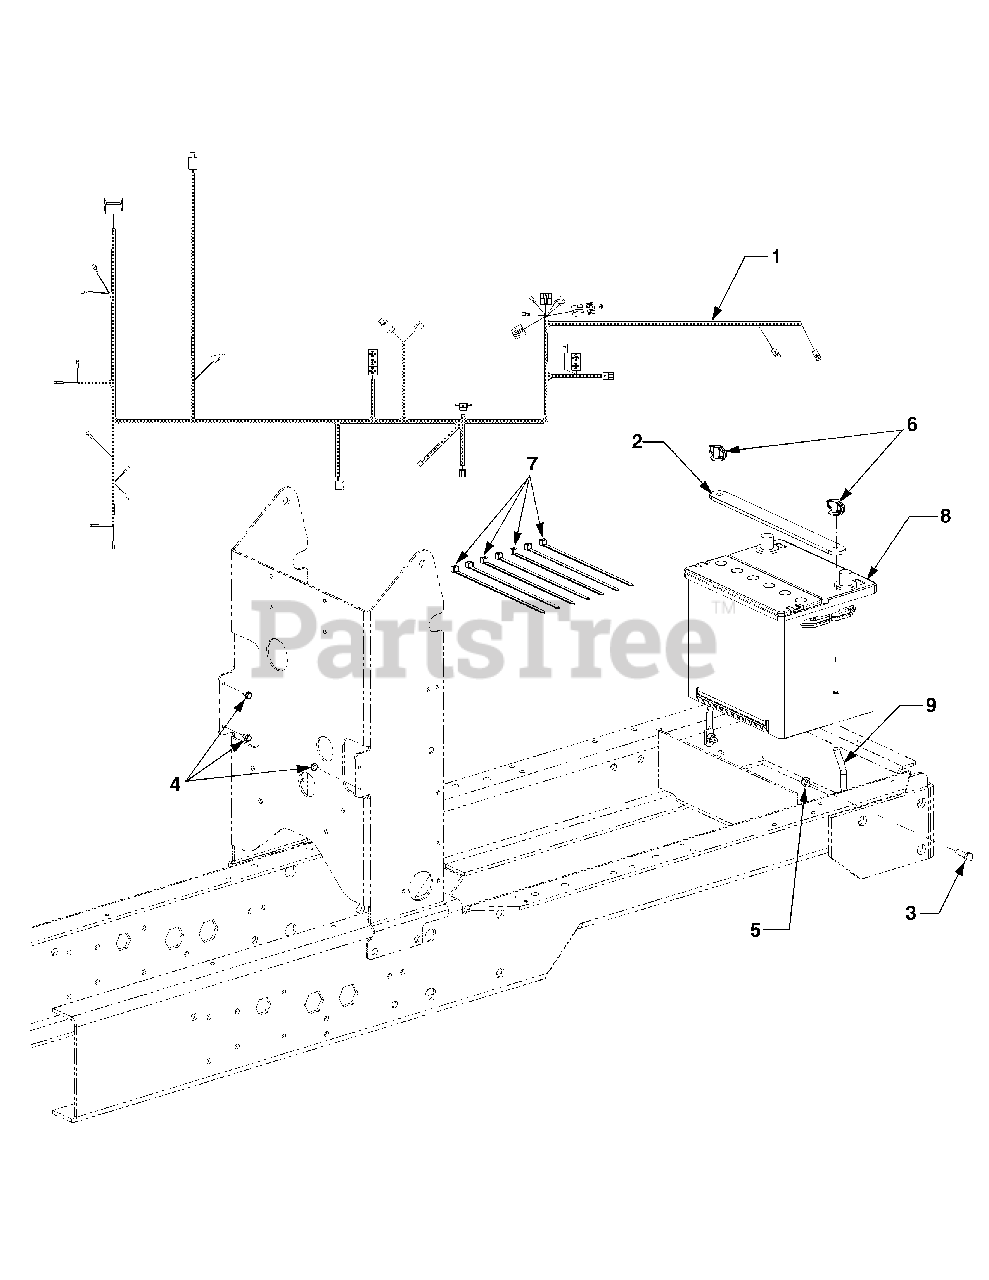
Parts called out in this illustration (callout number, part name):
1	Harness, Main Wire
2	Strap, Battery Holddown
3	Screw, Hex Cap, 1/4-10 x .875 GR5
4	Screw, Hex Wash Hd. Tapp #10-16 x .5
5	Nut, Hex Nylon Insert Lock, 1/4-20
6	Nut, Wing w/Bell Washer, 5/16-18
7	Tie, Cable
8	Battery, 500 cca Dry
9	Rod, Battery Holddown
